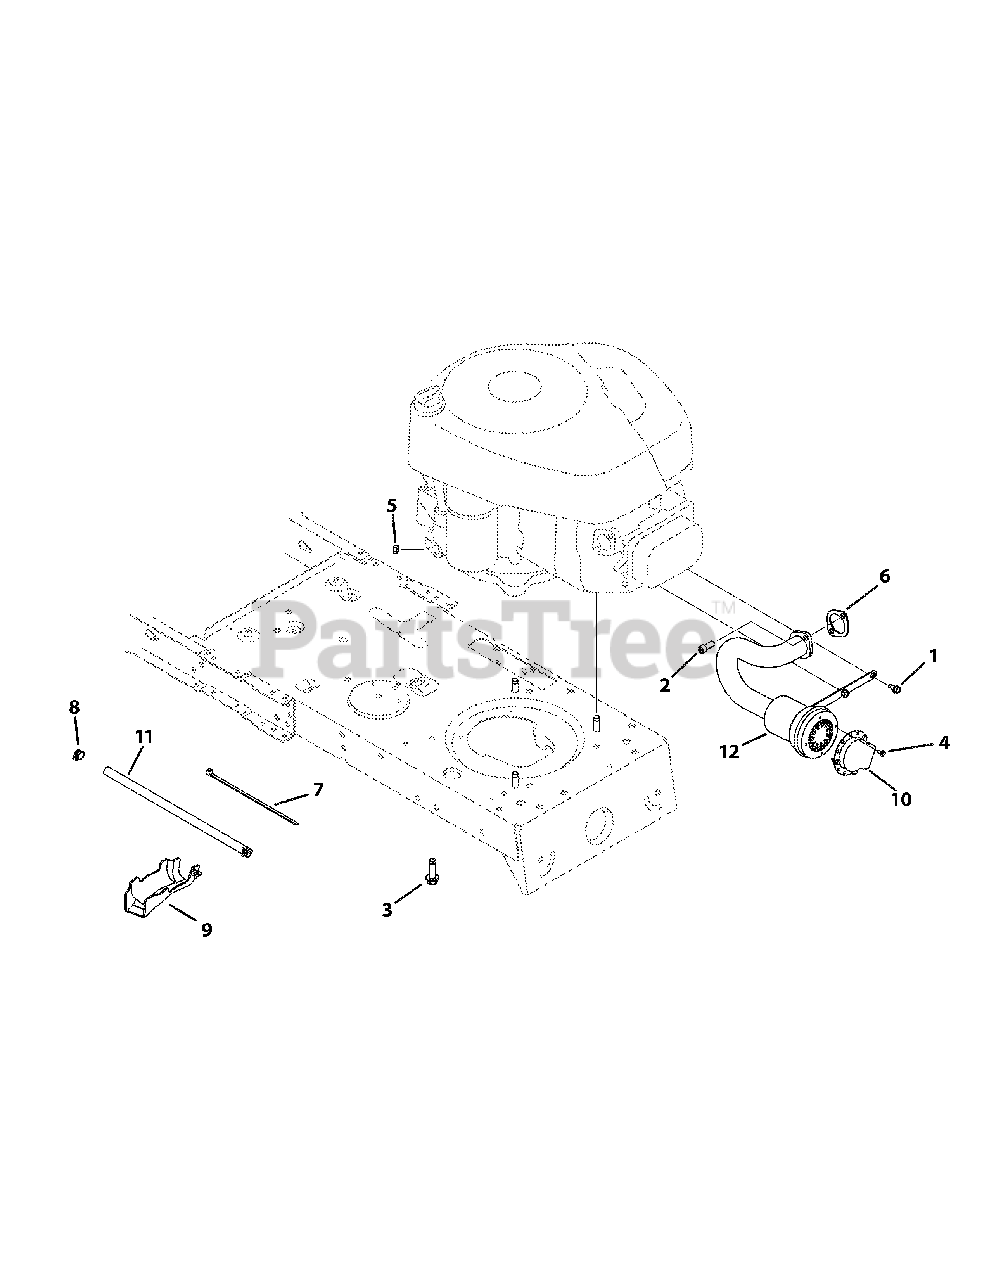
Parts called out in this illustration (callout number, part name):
1	Screw, 1/4-20 x .500
2	Socket Screw, 5/16-18 x .750
3	Screw, 3/8-16 x 1.0
4	Screw, 8-18 x .500
5	Sems Nut, 1/4-20
6	Exhaust Gasket, 10 HP Briggs
7	Cable Tie
8	Clamp Hose, .490 diameter
9	Oil Drain Sleeve
10	Muffler Deflector
11	Fuel Hose, Low Permeation
12	Muffler
